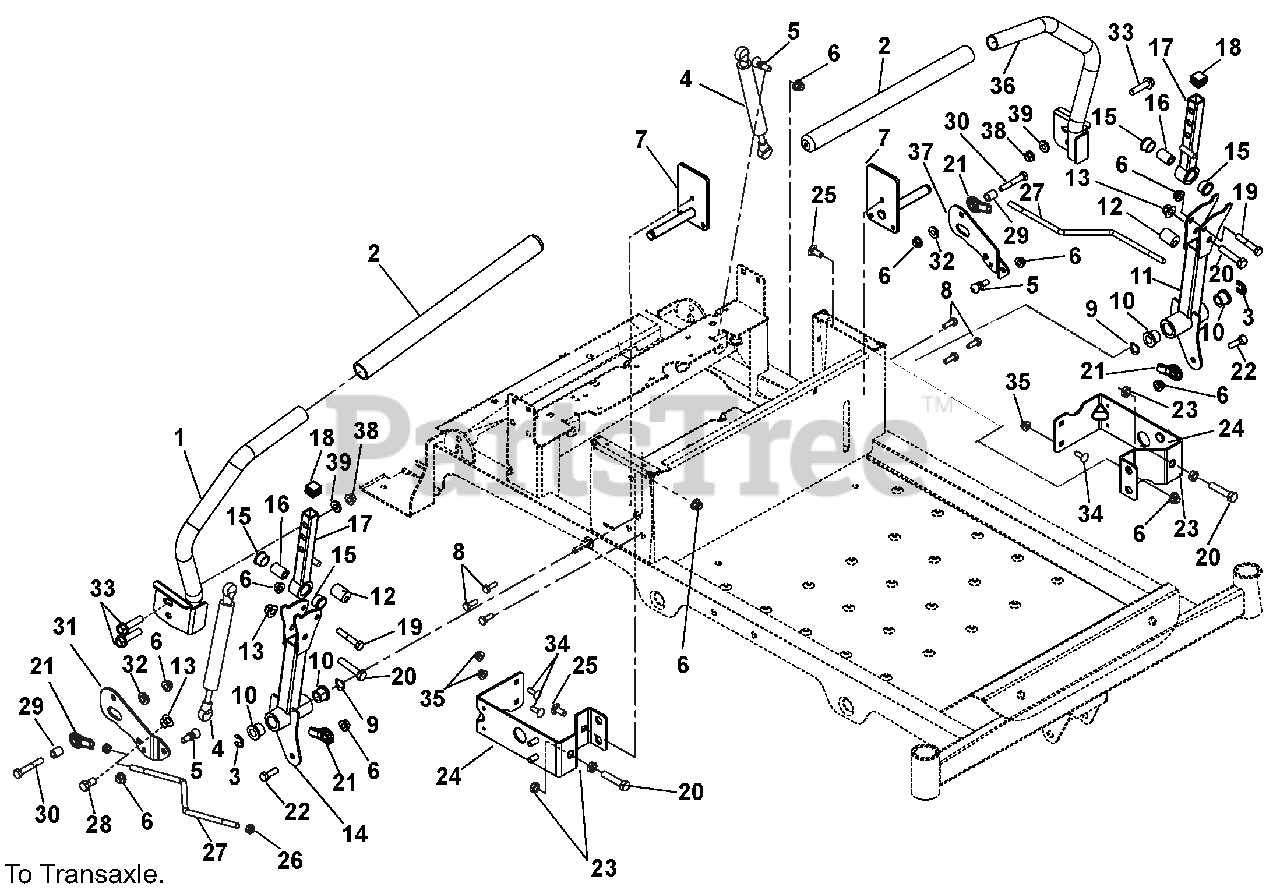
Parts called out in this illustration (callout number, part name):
1	WMT, STEERING HANDLE
2	GRIP, HANDLEBAR 15" FOAM
3	RG-RTNG-EXT .500X.042 (E)
4	DAMPER, STABILUS
5	STUD- BALL
6	@NUT-LK-NYL-FLG .31-18 YWZC
7	WMT, STEERING SHAFT
8	SCR-TAP .25-20X.50 HWH TR YWZ
9	WSHR-WAVE .50X.75X.015 .13FRHT
10	BSHG-FLG .500X.750X.625X.937
11	WMT, LOWER CONTROL ARM
12	BSHG, ECCENTRIC .328X.750X.970
13	@NUT-LK-NYL-FLG .38-16 YWZC
14	WMT, LOWER CONTROL RH
15	BSHG-FLG, .625X.75X.450X.875
16	SPACER, .375X.625X.970 (PM)
17	WMT, UPPER CONTROL ARM
18	CAP PLUG, SQ 3/4-14-20 RIBBED
19	@BLT-HEX .31-18X1.75 GR5 YWZC
20	BLT-HEX .375-16X1.750 FTD YWZC
21	ALIGNABALL, 5/16 RH THREAD
22	@BLT-HEX .31-18X1.00 GR5 YWZC
23	NUT-HEX-JAM .375-16 YWZC
24	WMT, STEERING STOP
25	@BLT-RHDSSQNK .31-18X.75 G5YZ
26	NUT-JAM .31-24 YWZC
27	WIREFORM, STEERING LINK
28	@BLT-HEX .38-16X.75 GR5 YWZC
29	SPACER, .328X.500X.625
30	@BLT-HEX .31-18X2.00 GR5 YWZC
31	PLATE, DAMPER RH
32	BSHG-FLG .316X.430X.225X.750
33	BLT-SERHFWH .375-16X1.25 YWZC
34	@BLT-RDHDSQNK .25-20X.75 G5YZ
35	@NUT-LK-NYL-FLG .25-20 YWZC
36	WMT, STEERING HANDLE LH
37	PLATE, DAMPER (LH)
38	@NUT-LK-CTR-JAM .375-16 YWZC
39	@WSHR-FL-STL.406X.812X.065 YWZ
